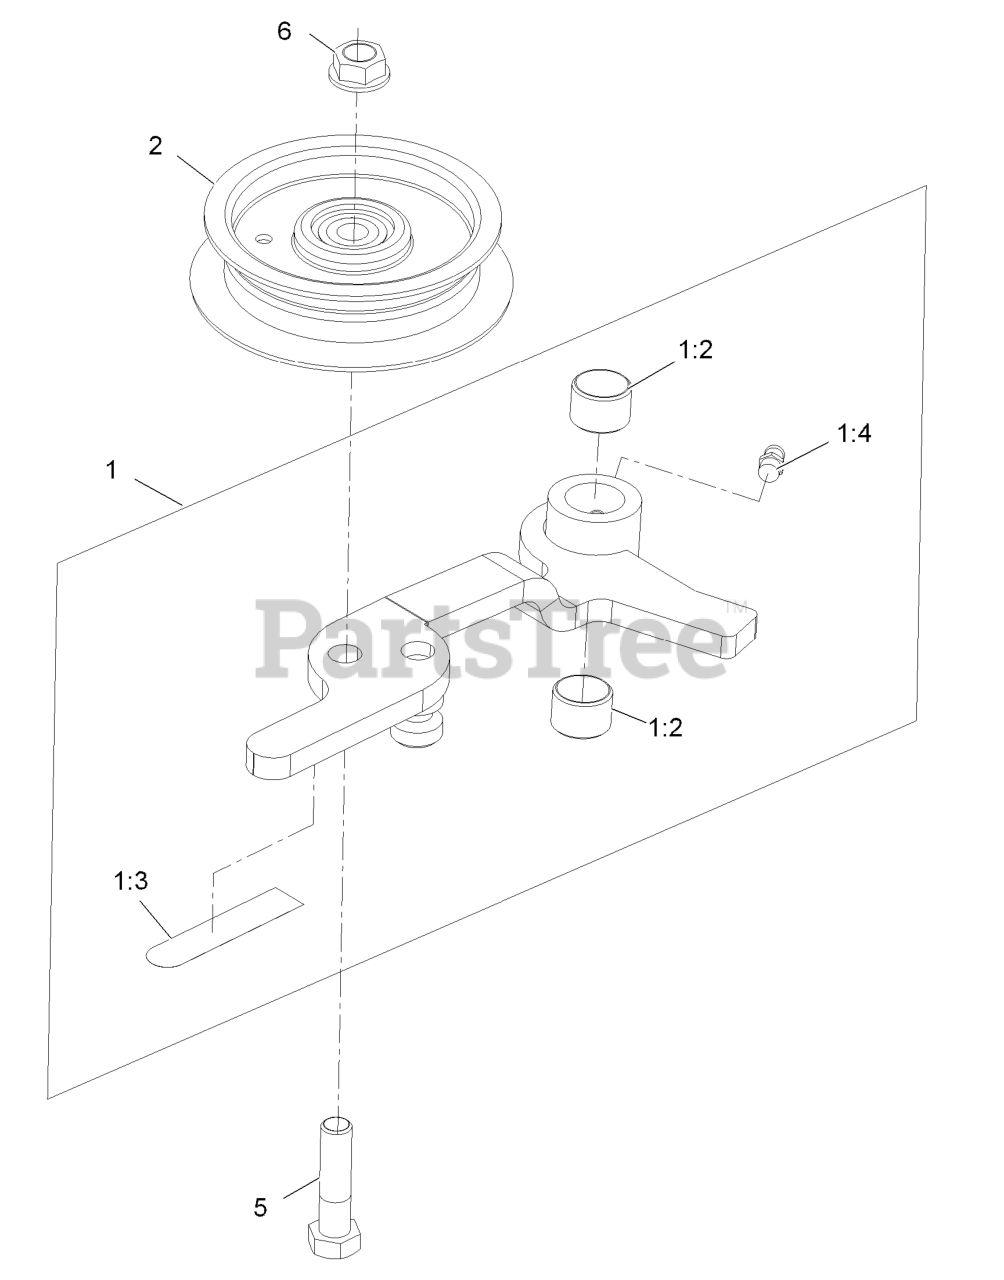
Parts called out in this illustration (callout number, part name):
1	Idler Assy With Bushings, Zerk, And Decal
1:2	Bearing
1:3	Decal-Warning
1:4	Zerk-1/4-28 Str
2	Idler-Flat
5	Screw-HH 3/8-16 X 1 1/2
6	Nut-Whizlock 3/8-16
